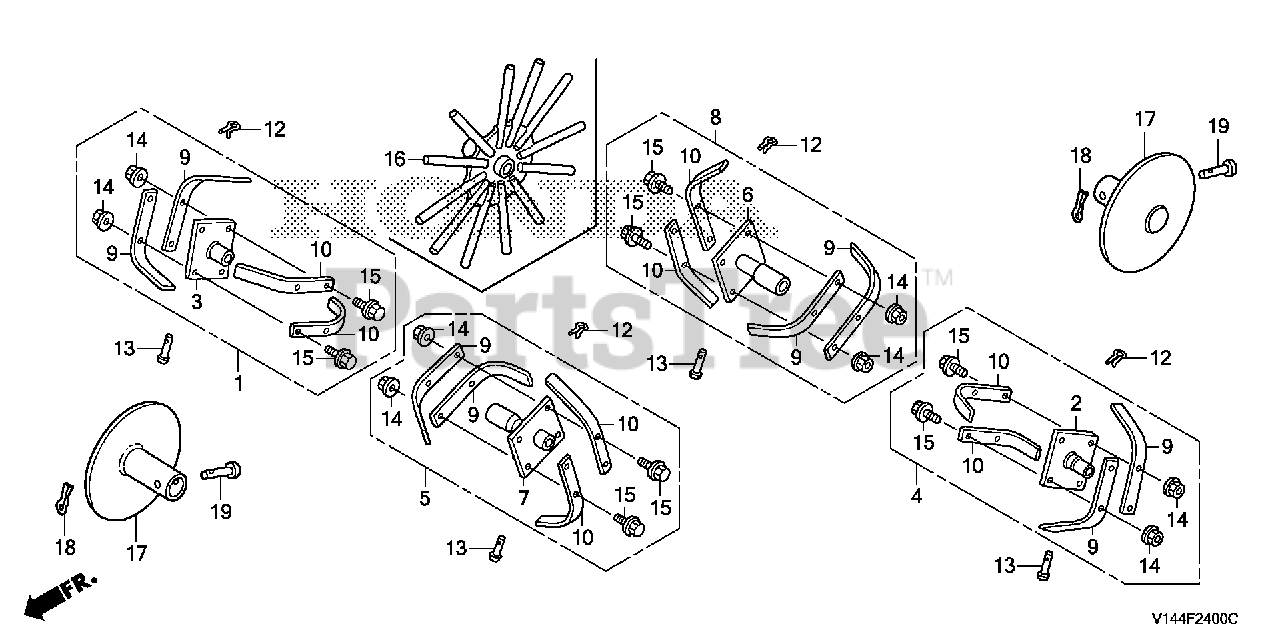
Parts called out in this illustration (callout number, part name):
1	PIPE, R. MAIN *NH1* (BLACK)
2	PIPE, L. ROTOR MAIN
3	PIPE, R. ROTOR MAIN
4	PIPE, L. MAIN *NH1* (BLACK)
5	PIPE, R. EXTENSION *NH1* (BLACK) (NOT AVAILABLE)
5	PIPE, R. EXTENSION *NH1* (BLACK)
6	PIPE, L. ROTOR EXTENSION
7	PIPE, R. ROTOR EXTENSION
8	PIPE, L. EXTENSION *NH1* (BLACK)
8	PIPE, L. EXTENSION *NH1* (BLACK) (N/A: SEE COMPONENTS)
9	TINE A, ROTOR
9	TINE, ROTOR (C)
10	TINE A, ROTOR
10	TINE, ROTOR (D)
12	PIN, SNAP (7MM)
13	PIN, WHEEL (8X35)
14	NUT, FLANGE (8MM)
15	BOLT, FLANGE (8X18) Use from Frame SN 1256673.
16	ROTOR, PICK-UP
